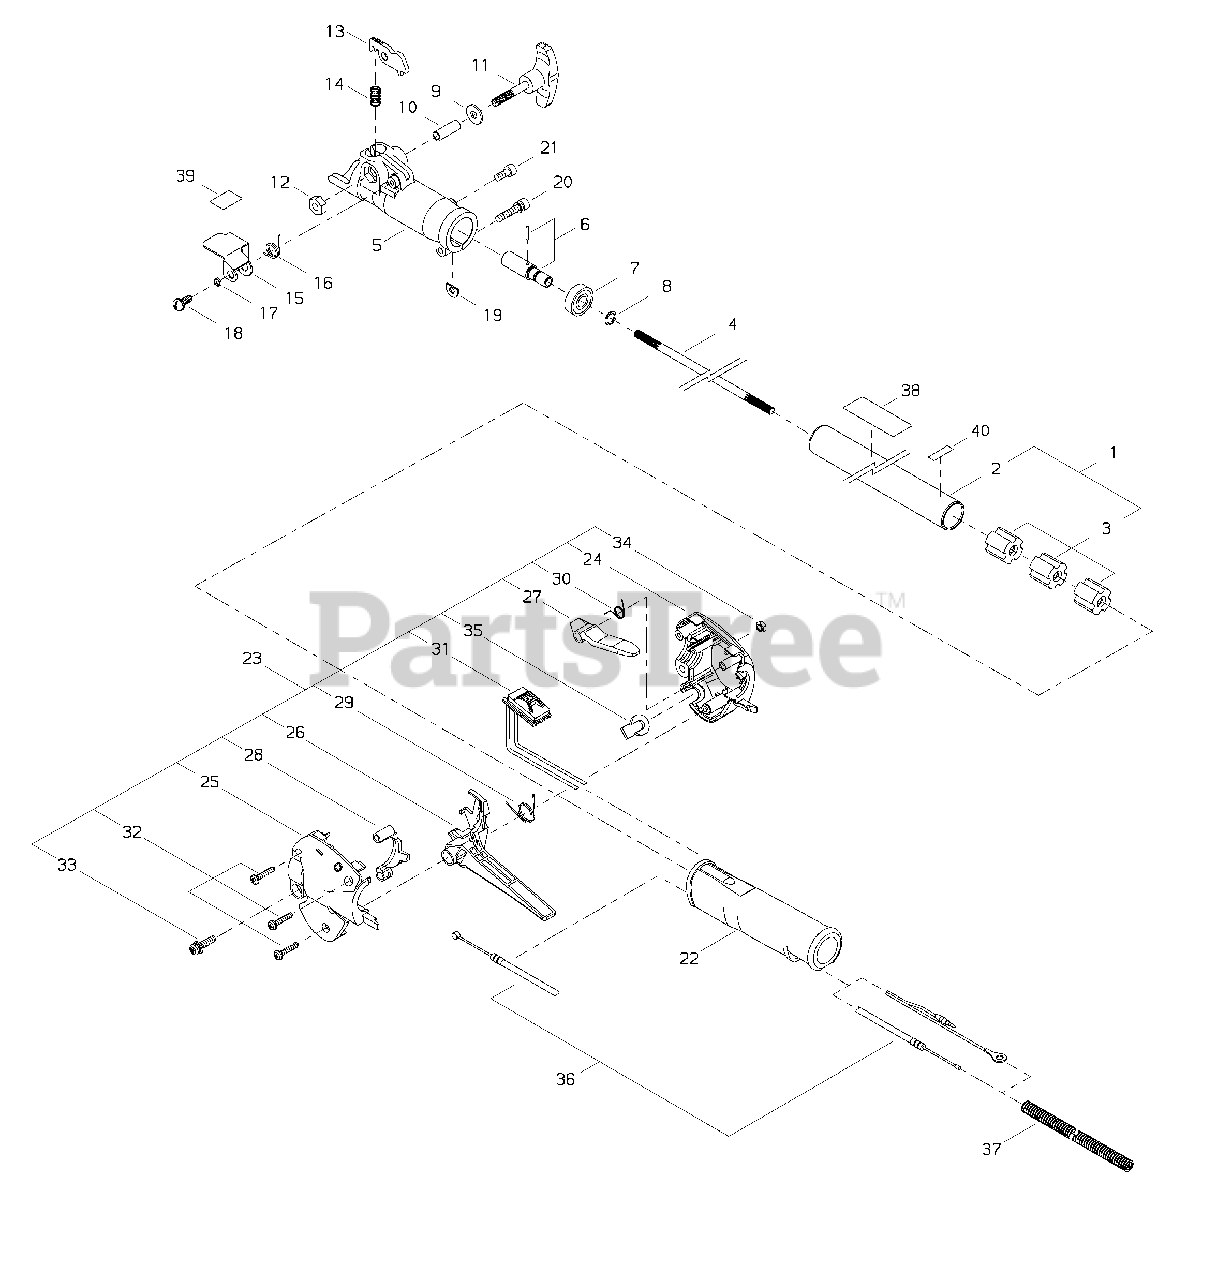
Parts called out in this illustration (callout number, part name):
1	MAIN PIPE ASSY
2	PIPE, MAIN
3	BUSHING
4	PIPE, MAIN
5	COUPLER
6	CONNECTOR, SHAFT
7	BEARING, BALL - 609ZZ
8	RING, RETAINING
9	WASHER
10	COLLAR
11	KNOB
12	NUT
13	LEVER, LOCK
14	SPRING
15	COVER
16	SPRING
17	COLLAR
18	SCREW - 5X12
19	SHIM
20	SCREW - 5X25
21	SCREW - 5X12
22	GRIP - REAR
23	THROTTLE ASSY
24	HANDLE, CONTROL - RIGHT
25	HANDLE, CONTROL - LEFT
26	TRIGGER, THROTTLE
27	LEVER, TRIGGER LOCKOUT
28	LOCKOUT, THROTTLE
29	SPRING
30	SPRING
31	SWITCH, IGNITION
32	SCREW - 4X20 -- TAPPING
33	SCREW - 5X20
34	NUT - 5
35	PLUG
36	CABLE, THROTTLE
37	TUBE
38	LABEL - CAUTION
39	LABEL - LATCH INSTRUCTION
40	LABEL - INSTRUCTION
